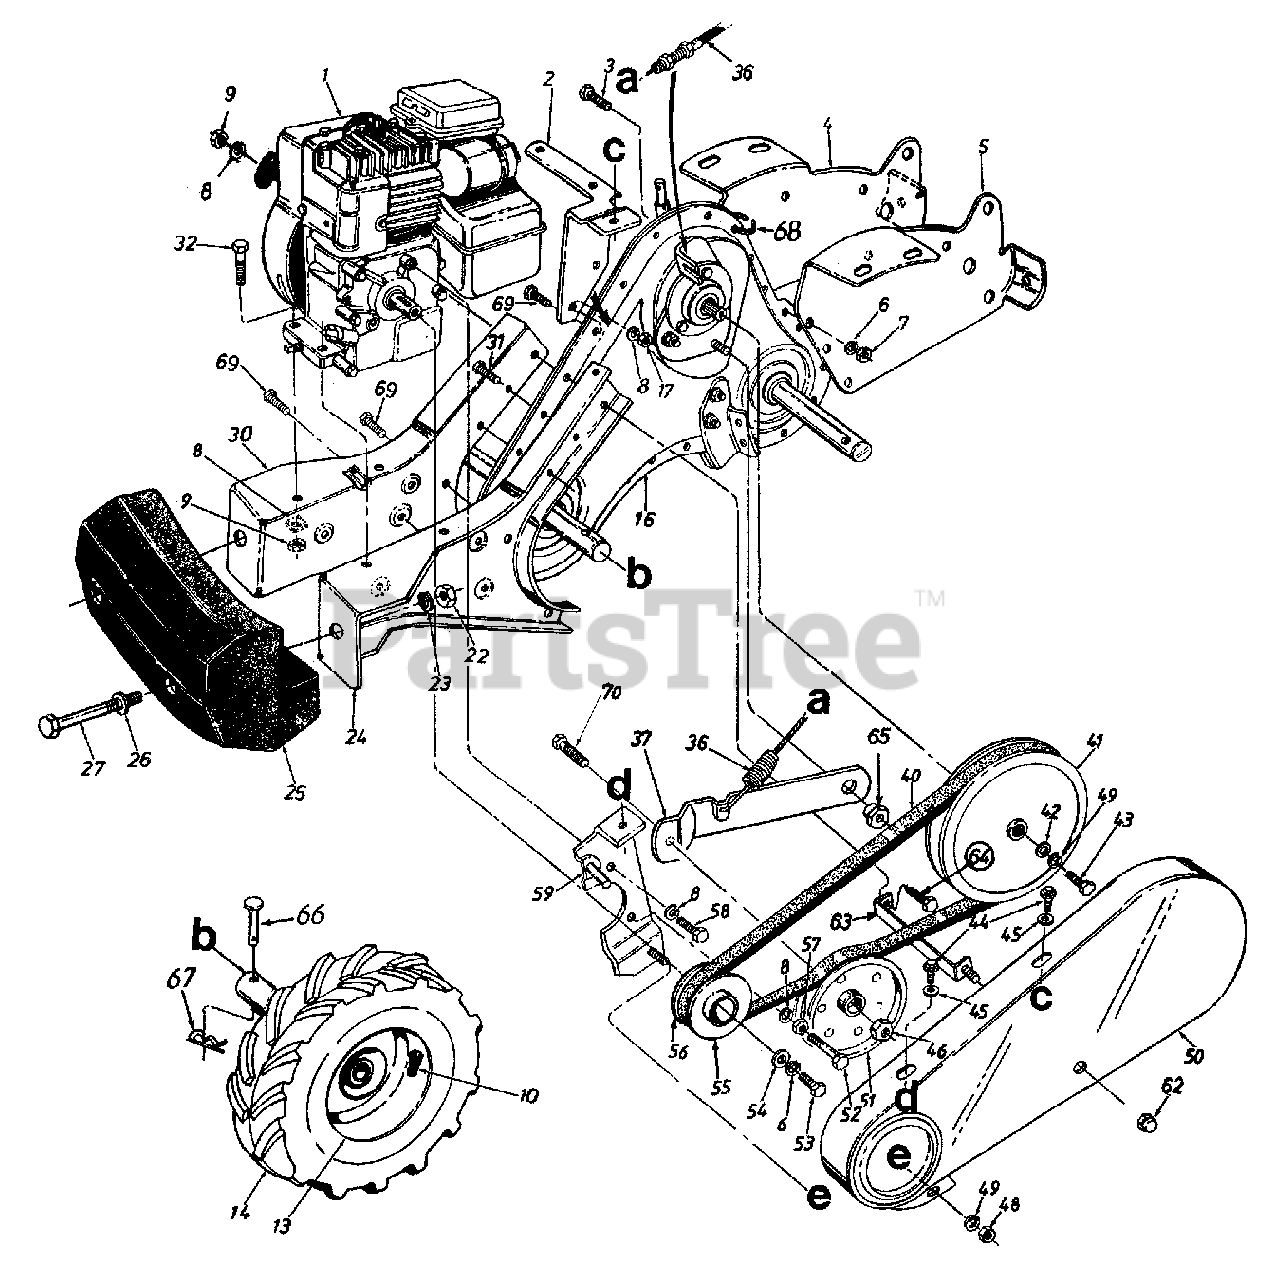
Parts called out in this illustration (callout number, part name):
1	Engine
7	Hex Nut 3/8-16 Thd.
8	L-Wash. 5/16" I.D.
9	Hex Nut 5/16-18" Thd.
10	Air Valve
16	Gear Case Ass'y. Comp.
17	Hex Nut 5/16-18 Thd.
22	Hex Nut 1/2-13 Thd.
23	L-Wash. 1/2" I.D.
26	Fl-Wash. .510" I.D. x 1.0"
27	Hex Bolt 1/2-13 x 5.00" Lg.
32	Hex Bolt 5/16-18 x 1.50"
36	Clutch Control Cable 46" Lg.
37	Idler Bracket
40	"V"-Belt
41	Fl-Pulley 8" O.D.
42	Fl-Wash. 1/4" I.D. x .93" O.D.
43	Hex Bolt 1/4-28 x .75" Lg.
44	Hex Wash. Hd. S-Tap Scr. 1/4-20 x .50" Lg.
45	Fl-Wash. .281" I.D. x .625"
46	Jam Nut 3/8-16 Cent. Loc.
48	Hex Nut 1/4-20 Thd.
49	L-Wash. 1/4" I.D.
51	Fl-Idler w/Flanges 3.75" O.D.
52	Hex Bolt 5/16-24 x 1.75"
53	Hex Bolt 3/8-24 x 1.00" Lg.
55	Outer Engine Pulley Half
56	Inner Engine Pulley Half
57	Hex Nut 5/16-24 Thd.
58	Hex Bolt 5/16-24 x .62" Lg.
63	Belt Cover Brkt. Ass'y.
64	Hex Bolt 5/16-18 x 1" Lg. (Gr. 5)
65	Shld. Nut
66	Clevis Pin
67	Hairpin Clip
68	Cable Tie-Self Clinching
69	Screw 5/16-18 x 1"
70	Hex Hd. Cap Scr. 3/8-16:1.25" Lg.
